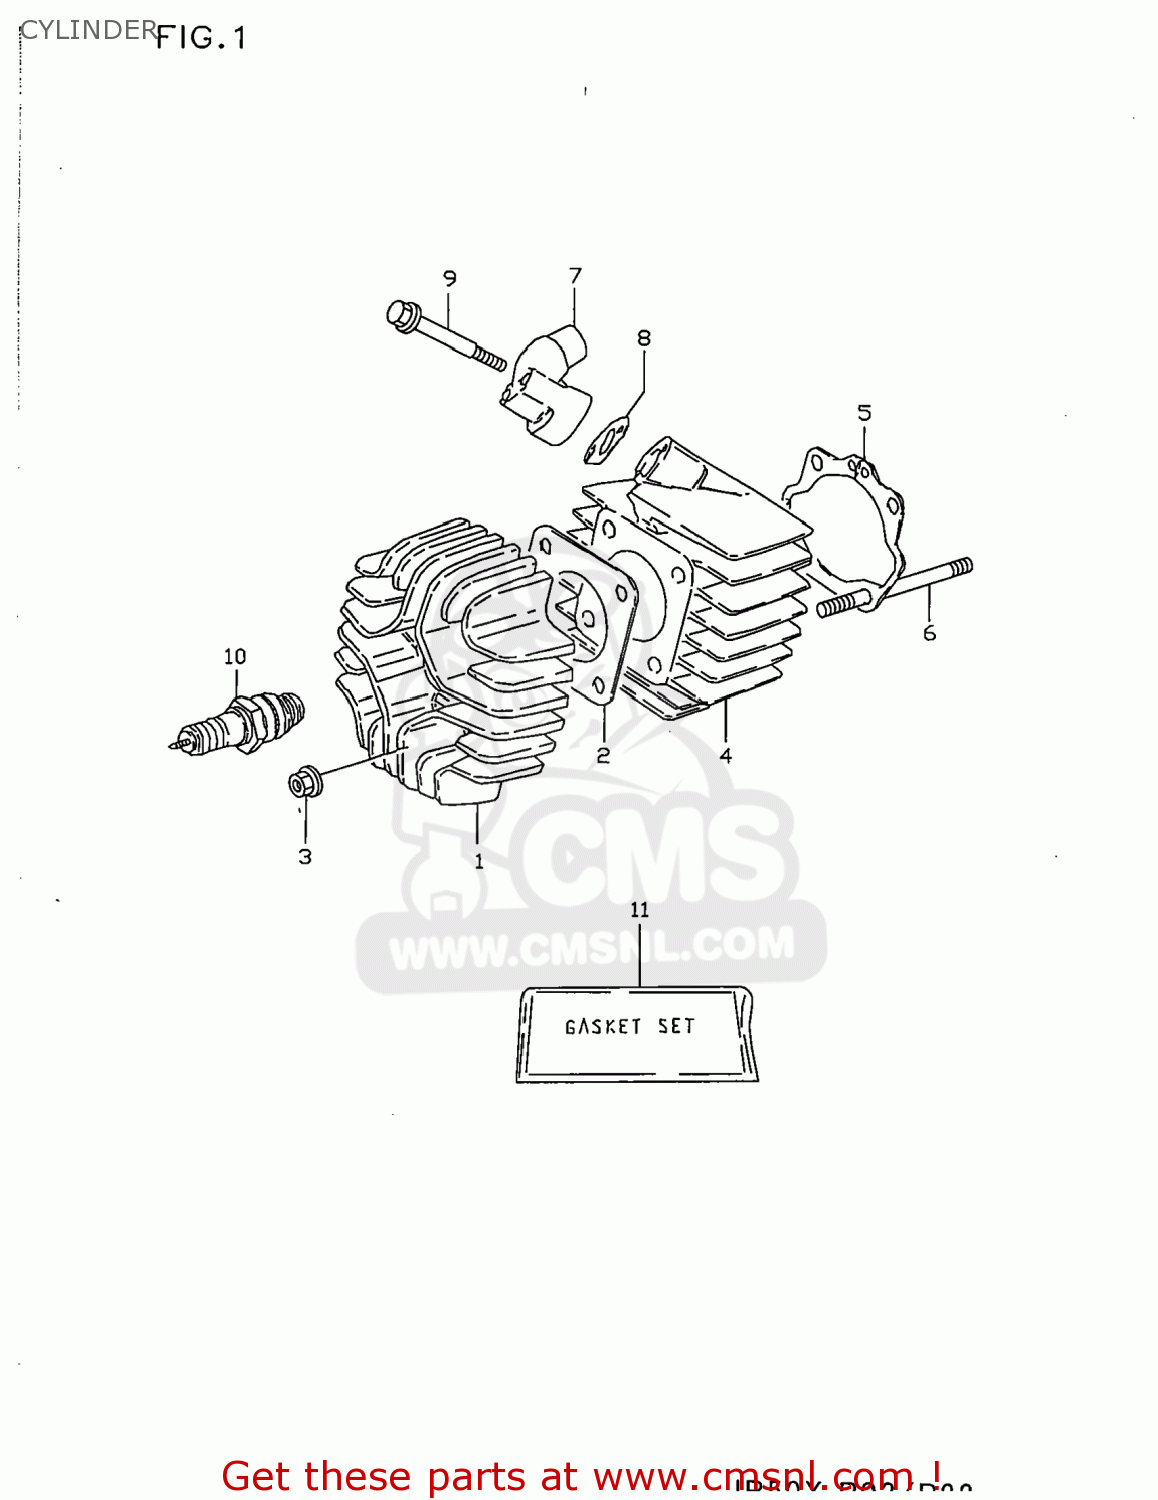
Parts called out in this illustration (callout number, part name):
1	HEAD,CYLINDER
2	GASKET,CYLINDER HEAD (NAS)
3	NUT
4	CYLINDER
5	GASKET,CYLINDER (NAS)
6	BOLT,STUD
7	PIPE,INTAKE
8	GASKET,INTAKE PIPE (NAS)
9	BOLT
10	SPARK PLUG W14FPR-UL
11	GASKET SET (NAS)
